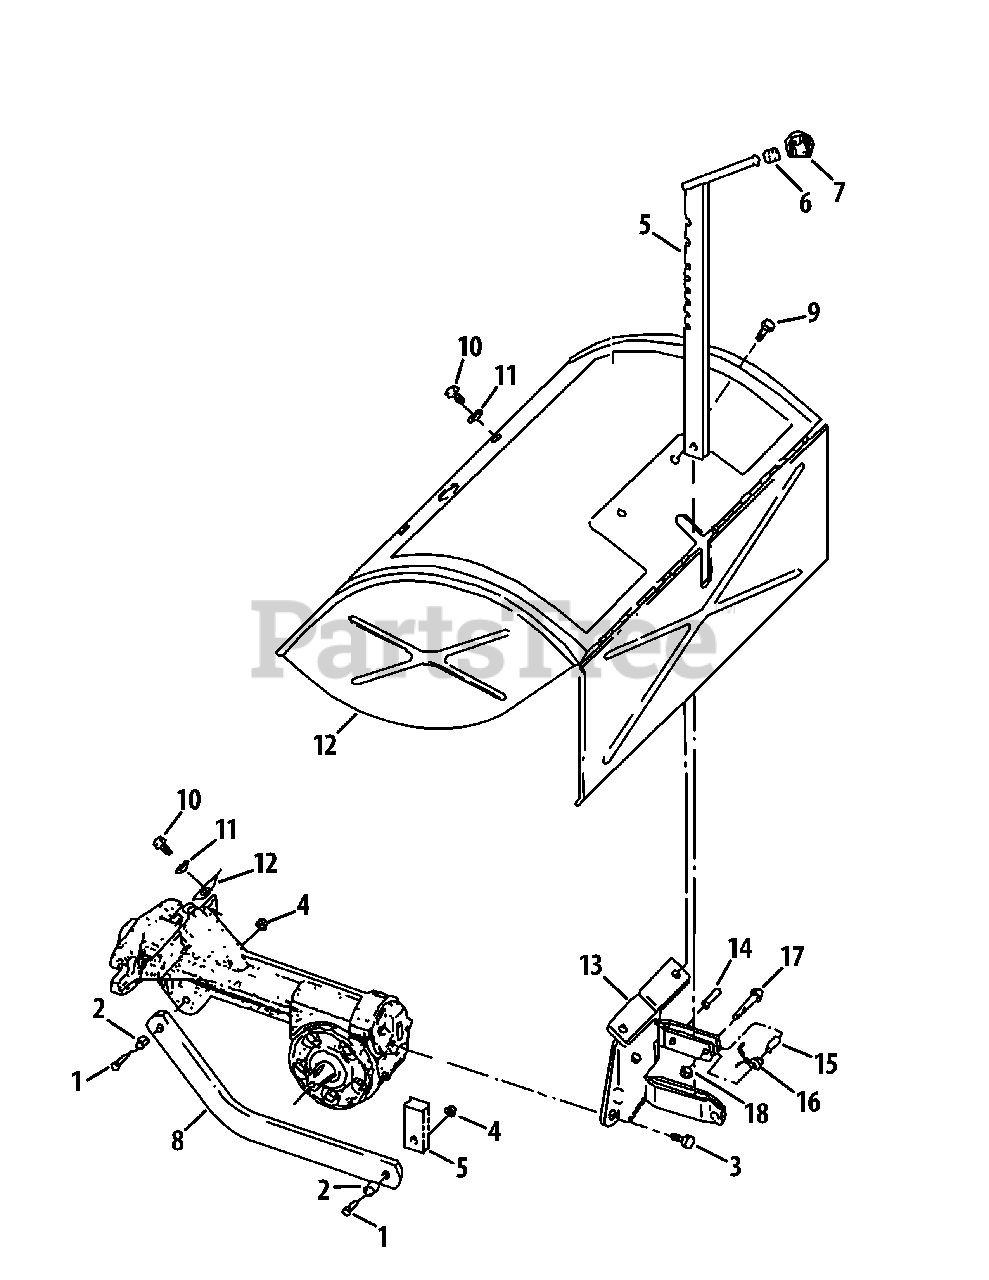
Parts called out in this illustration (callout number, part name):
1	Hex Bolt, 3/8"-16 x 1-1/4"
2	Bushing Spacer, .5 x .375 x .3
3	Hex Flange Bolt, 5/16"-18 x .625
4	Flangelock Nut, 3/8"-16
5	Depth Regulator
6	Retaining Ring
7	Depth Regulator Knob
8	Depth Regulator Bar Drag
9	Thread-forming Screw, 1/4"-20 x 1/2"
10	Hex Flange Bolt, 5/16"-18
11	Washer, 1.12 x .34 x .06
13	Hood Bracket
14	Roll Pin (Spirol), 1/4" x 1"
15	Split Spacer
17	Hex Bolt, 1/4"-20 x 1"
18	Locknut, 1/4"-20
